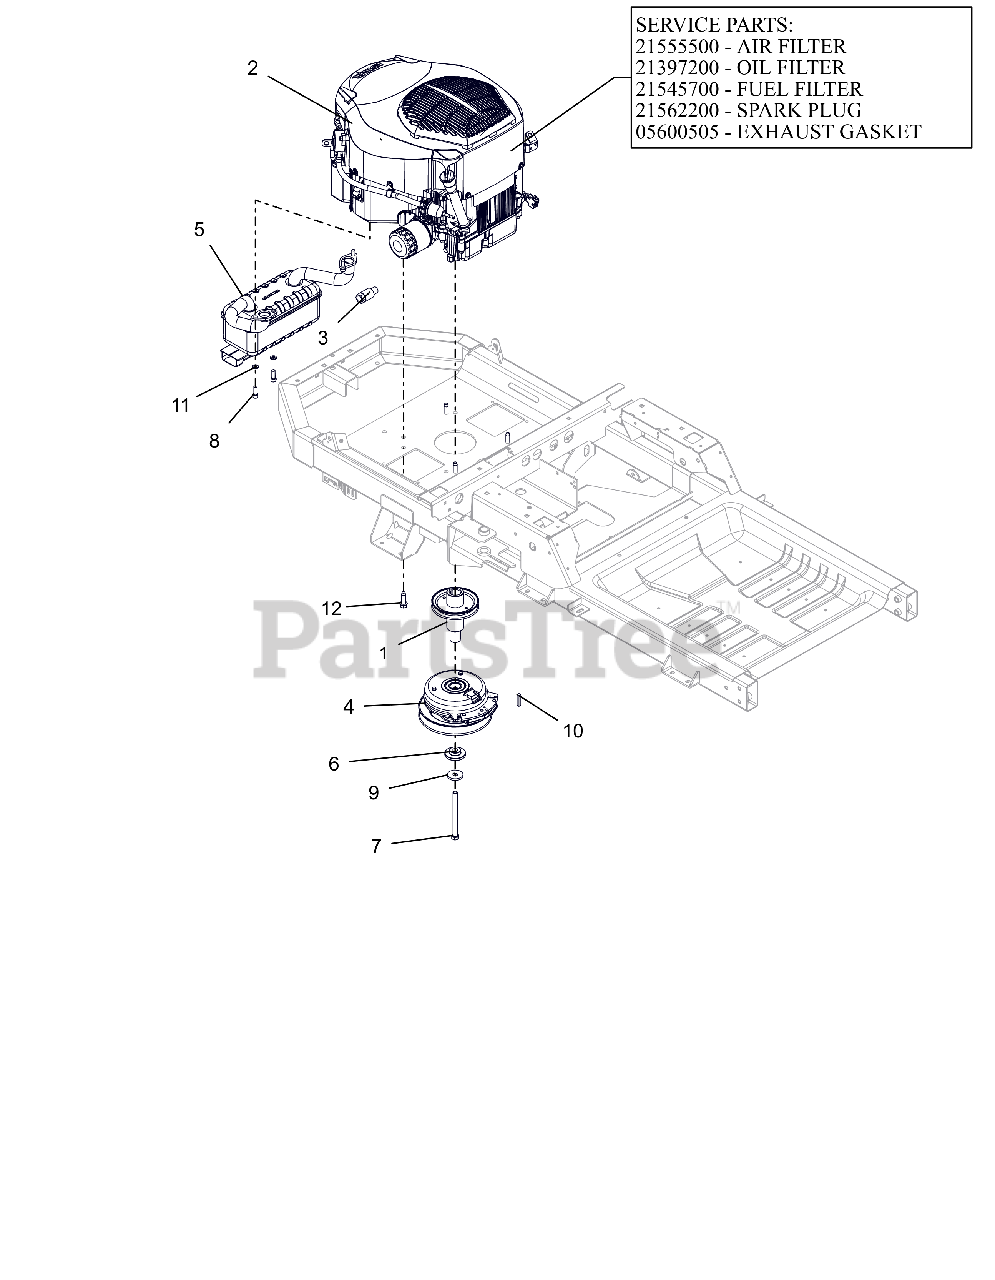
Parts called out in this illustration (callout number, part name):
1	WLDMT, DRIVE SHEAVE (LG XL)CZC
2	ENGINE, KOHLER 24HP TWIN
2	AIR CLEANER, KOHLER
2	FILTER, OIL - KOH CV20
2	FILTER-FUEL KOHLER COURAGE PRO
2	PLUG, SPARK (RFI)
2	GASKET, MUFFLER COURAGE TWIN
3	DRAIN, OIL
4	CLUTCH,105FTLB MONOPOLE 6.83"
5	MUFFLER, KOHLER
6	BSHG-FLG .469X1.06X.574X2.0
7	BLT-HEX.438-20X5 GR8 YZ NYTORQ
8	SCR-CAP .31-18X.88 S/HD G8 ZCC
9	WASHER, 7/16" SPRING DISK
10	KEY-SQ .25 X 1.25 X .25 SAE
11	WSHR,LK-REG .312X.078 ZCC
12	SCR,TAP .375-16X1.25HWH TR ZCC
